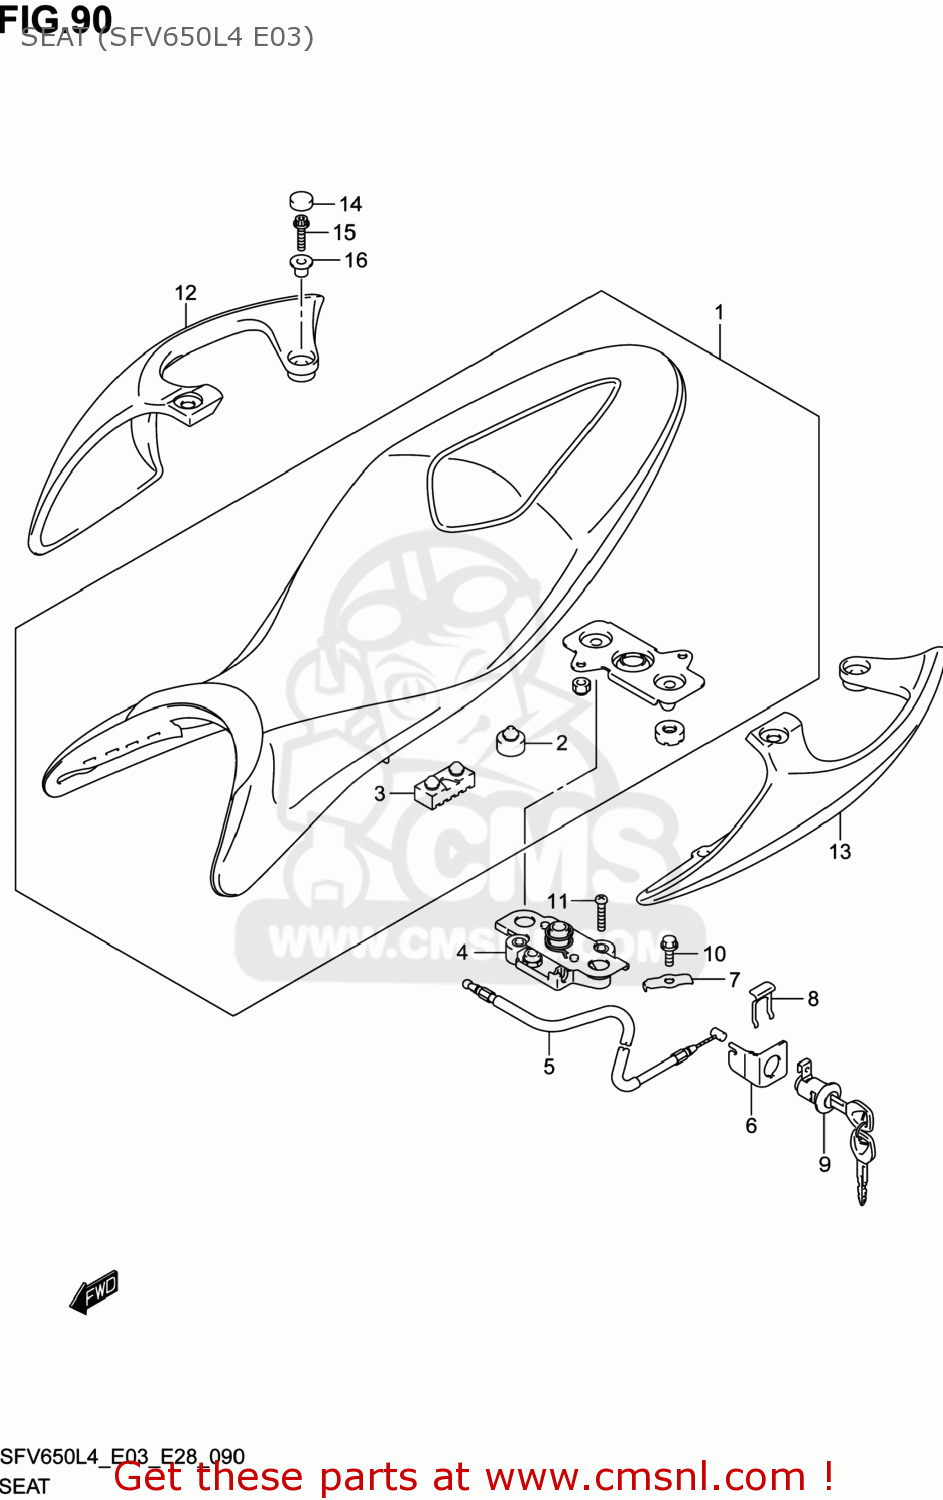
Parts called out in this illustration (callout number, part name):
1	SEAT ASSY
2	CUSHION
3	CUSHION
4	BRACKET,STRIKER SUPPORT
5	CABLE,SEAT LOCK
6	GUIDE,SEAT LOCK CABLE
7	GUIDE,SEAT LOCK CABLE
8	PLATE,SEAT LOCK ASSY
9	LOCK SET,SEAT
10	BOLT
11	SCREW
12	HANDLE,PILLION RIDER,R
13	HANDLE,PILLION RIDER,L
14	CAP
15	BOLT(8X25)
16	WASHER
